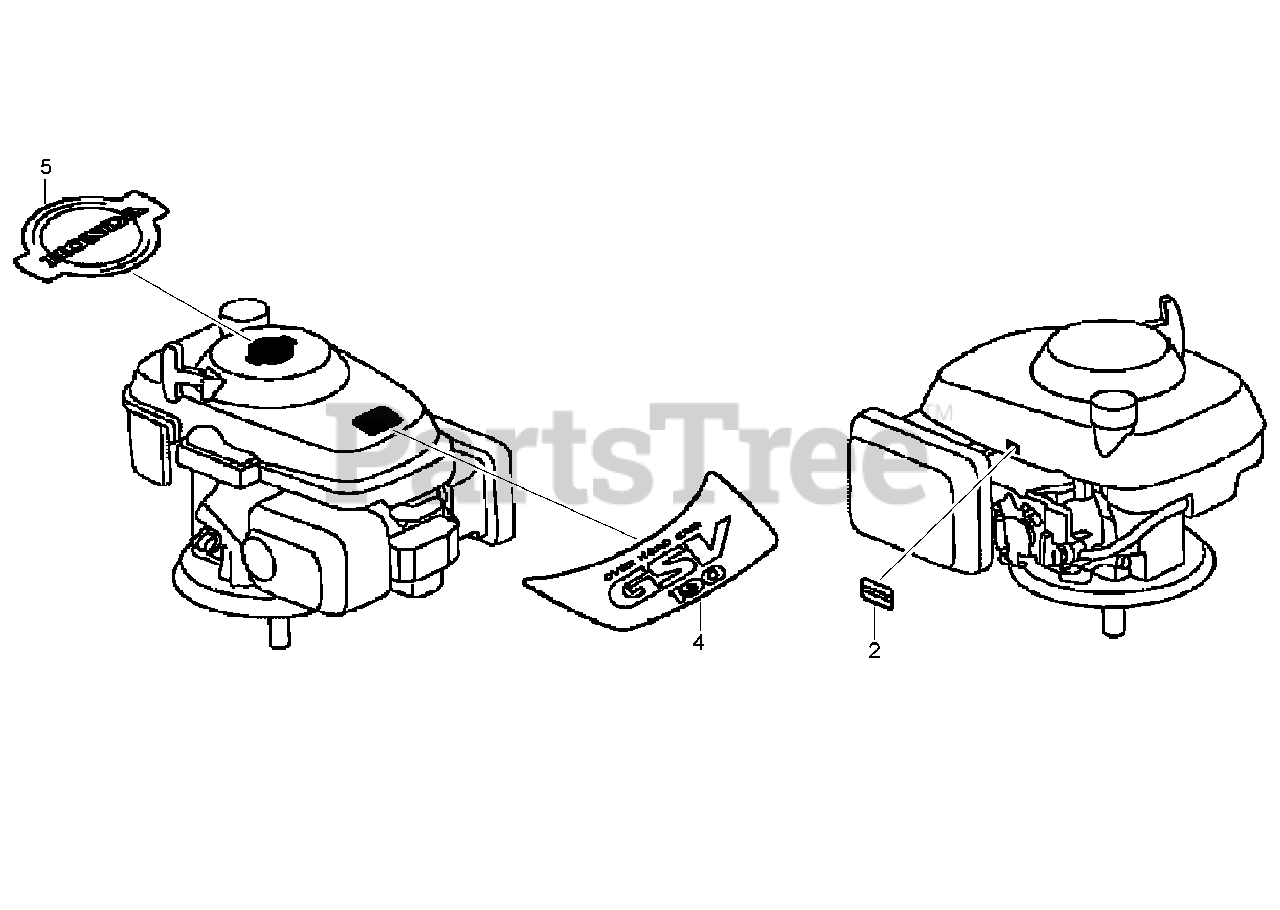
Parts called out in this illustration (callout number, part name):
2	LABEL-WARNING (NOT CERTIFIED FOR SALE)
4	MARK, EMBLEM (GSV190)
5	MARK, RECOIL COVER
